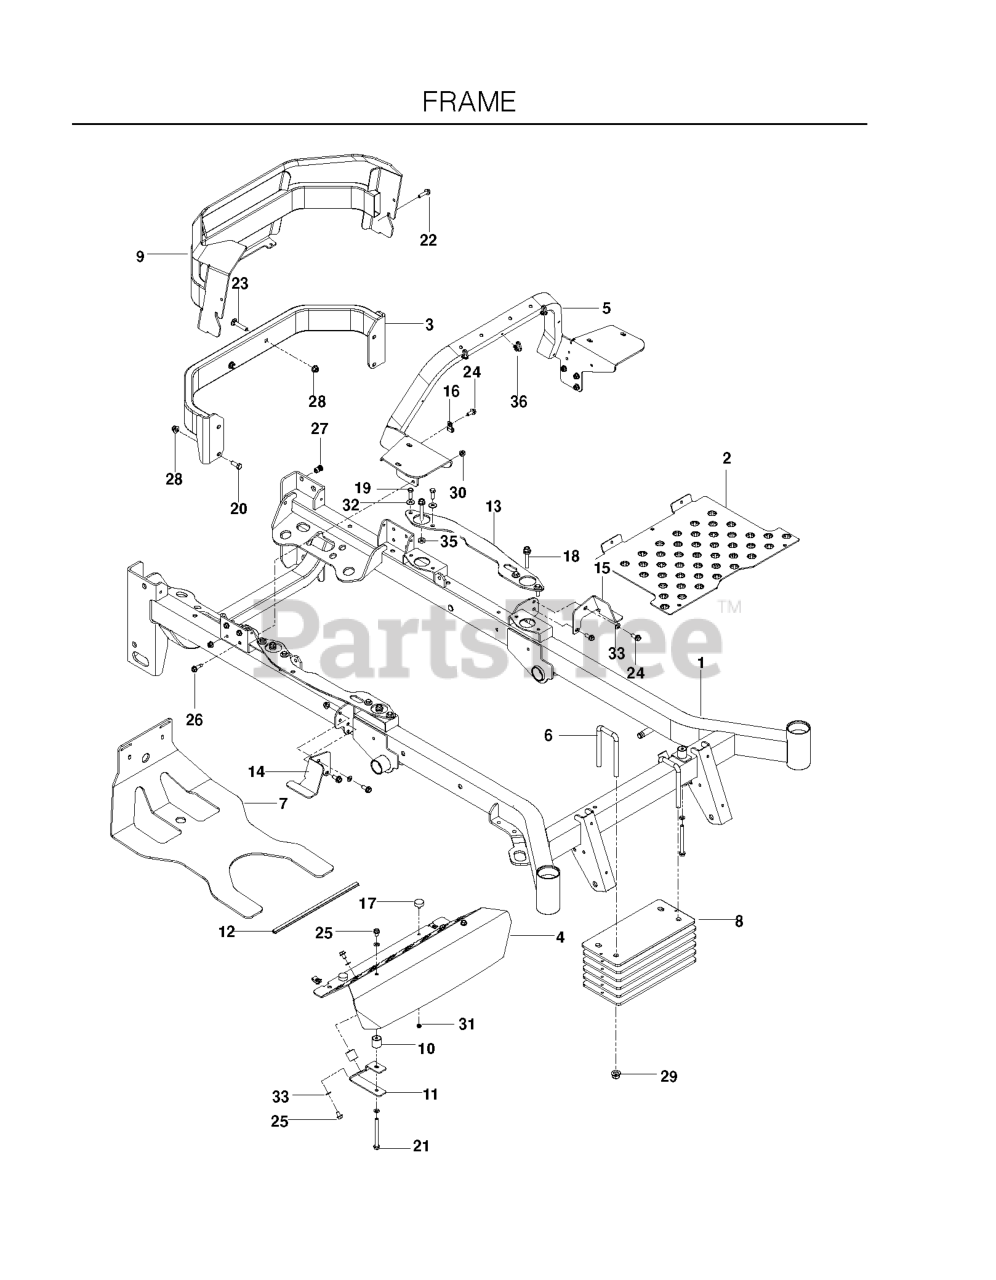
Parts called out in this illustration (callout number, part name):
1	FRAME.W/DECALS.PZ6029/PZ29
2	PLATE, FLOOR PAN, OR
3	BUMPER.REAR.W/DECALS
4	PLATE, FOOT REST, OR
5	CROSS MEMBER, GRAY
6	LINKAGE, U-BOLT
7	PLATE, SKID, BLACK
8	PLATE, WEIGHT BLK
9	GUARD, REAR W/DECALS
10	MOUNT, F/F INSERT
11	BRACKET, REST MOUNT
12	RP.FLEX TRIM, BLK-LENGTH 1 FT
13	STRAP.FRAME.BLACK
14	XX MOUNT, TANK, RT-BLK
15	MOUNT, TANK, LT-BLK
16	DOUBLE TUBE CLAMP
17	BUMPER, 1/4-20 STUD, 1/4
18	HHFS 3/8-16 X 2-1/4 GR 5 ZD
19	HCS 5/16C X 1
20	HCS 3/8-16X1.GRD.5.ZD
21	HHFS 5/16-18 X 3 3/4
22	HHFS 5/16-18 X 1.25 TPBLT GD 5
23	RHSNB 3/8C X 2
24	HHFS 5/16-18 X 3/4
25	SCR 5/16-18 X 1/2 SELFTAP ZN
26	RP BLT 5/16-18 X 1 THRD FORM D
27	NUTSERT 5/16-18 THICK GRIP
28	NUT 3/8-16 HEX FLG NYLOC ZD
29	NUT, 1/2-13 HEX FLG NYLOC ZD
30	5/16-18 NYLOC FLANGE NUT
31	JAM NUT 1/4C (2 2 PW01)
32	WASHER 5/16 FLAT
33	WASH 5/16 DISC SPRING ZD
35	WASHER 3/8 X 3/4 X .187 TK
36	TIE WRAP, 8-3/8", W/CLIP
